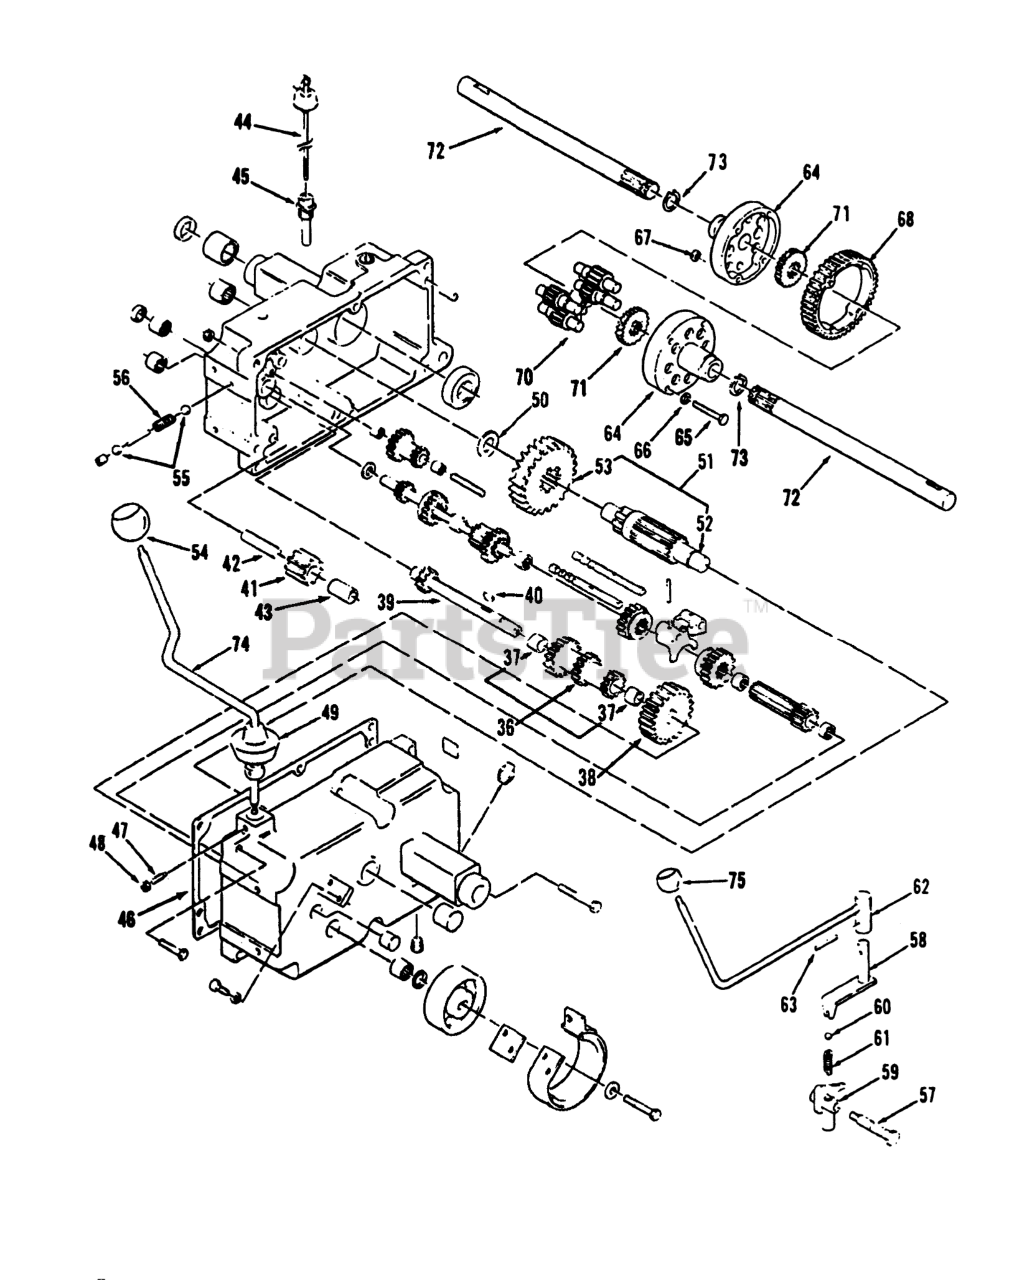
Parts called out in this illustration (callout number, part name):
36	GEAR-CLUSTER
37	BUSHING-BRONZE
38	GEAR-CLUSTER SHAFT
39	Cluster Shaft
40	KEY-WOODRUFF
41	GEAR/BUSHING ASM-REVERSE IDLER
42	PIN-DIFFERENTIAL
43	BUSHING
44	Dipstick
45	NIPPLE-FILL, TRANSMISSION
46	GASKET-TRANSMISSION
47	SETSCREW
48	NUT-HEX
49	COVER-DUST
50	WASHER-THRUST
51	GEAR ASM
52	PINION SHAFT
55	BALL-DETENT
56	SPRING-SHIFT STOP
57	BOLT-DETENT
58	SHIFT ASM
59	SHIFT FORK ASM
60	BALL-DETENT
61	SPRING-SHIFT STOP
62	SHIFT ROD ASM
63	PIN-SPIROL
64	END CAP-DIFFERENTIAL
65	BOLT-HEX
66	WASHER
68	GEAR-DIFFERENTIAL RING, 43T
70	GEAR-PINION, 11T
71	GEAR-AXLE DIFFERENTIAL
72	AXLE-REAR
73	RING-SNAP
74	ASM-Rod
75	Knob
